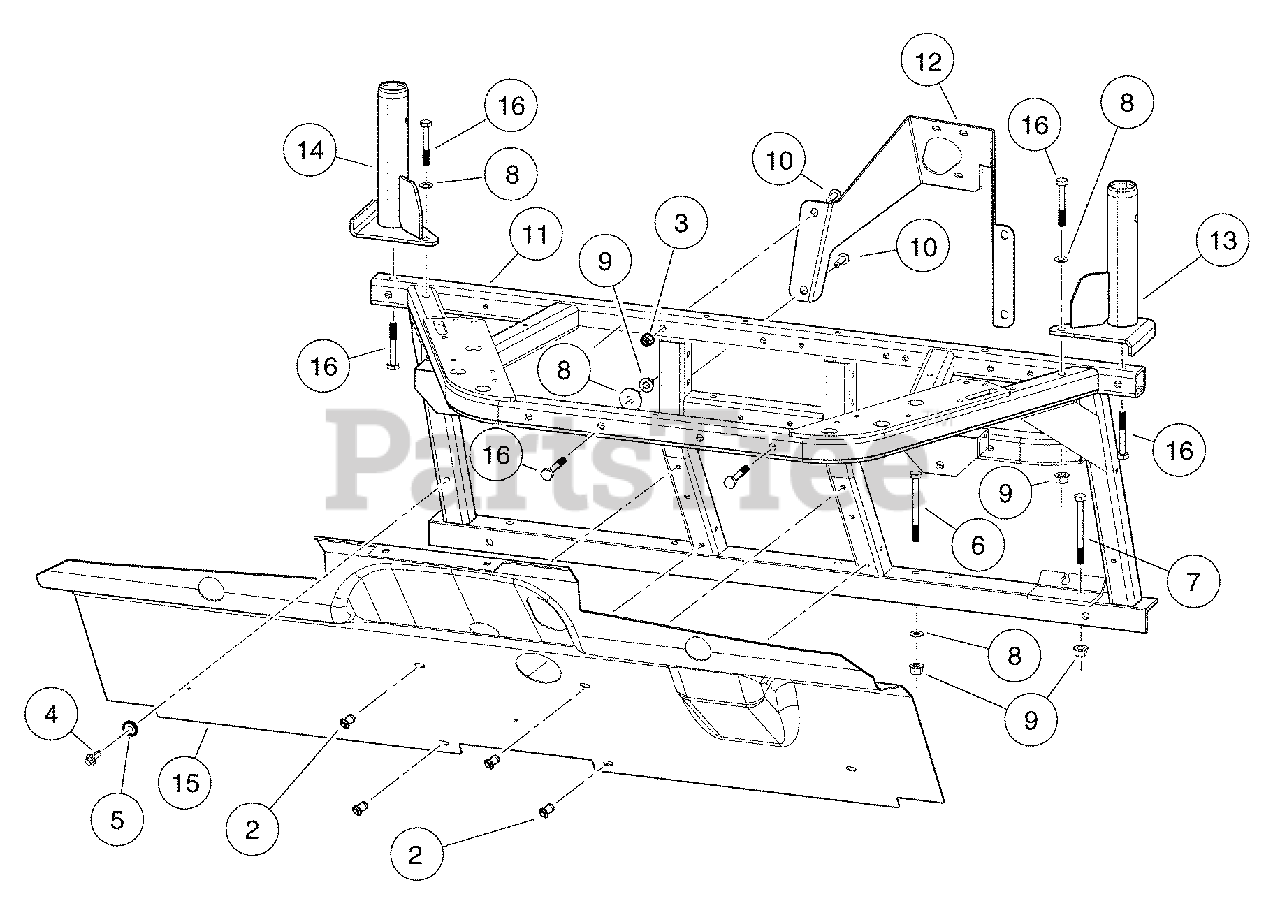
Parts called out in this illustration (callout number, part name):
1	Instl, Cowl Weldmnt/Splash Guard
2	Blind Rivet, Push Type
3	Nut,m8,all Metal Lock
4	M8-125x20 Taptite
5	Washer, Flat, 3/8, Blk Fin
6	Bolt, M10x150x100
7	Bolt, M10 X 150 X 110 Black
8	Washer Hard,m10
9	Nut Flg M10 X 15 Mech Def
10	Bolt Flanged Head, M8 X 125 X 65
11	Weldment, Dash, Front
12	Bracket, Column, Steering
13	Weldment, Front, Base, ROPS, Right-Hand
14	Weldment, Front, Base, ROPS, Left-Hand
15	Guard, Splash, Gas Injection
16	Bolt, M10 X 150 X 65
